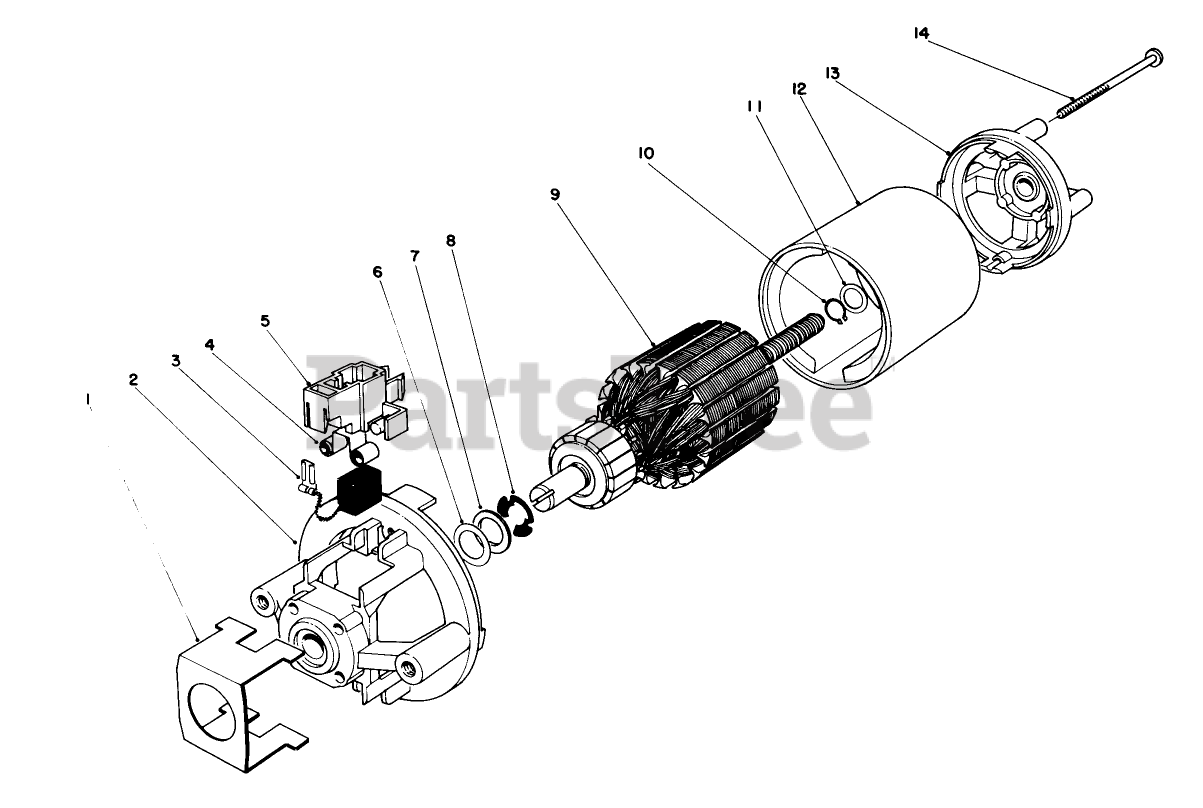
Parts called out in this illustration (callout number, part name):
3	Brush
4	Loose Parts Package
5	Brush Holder
